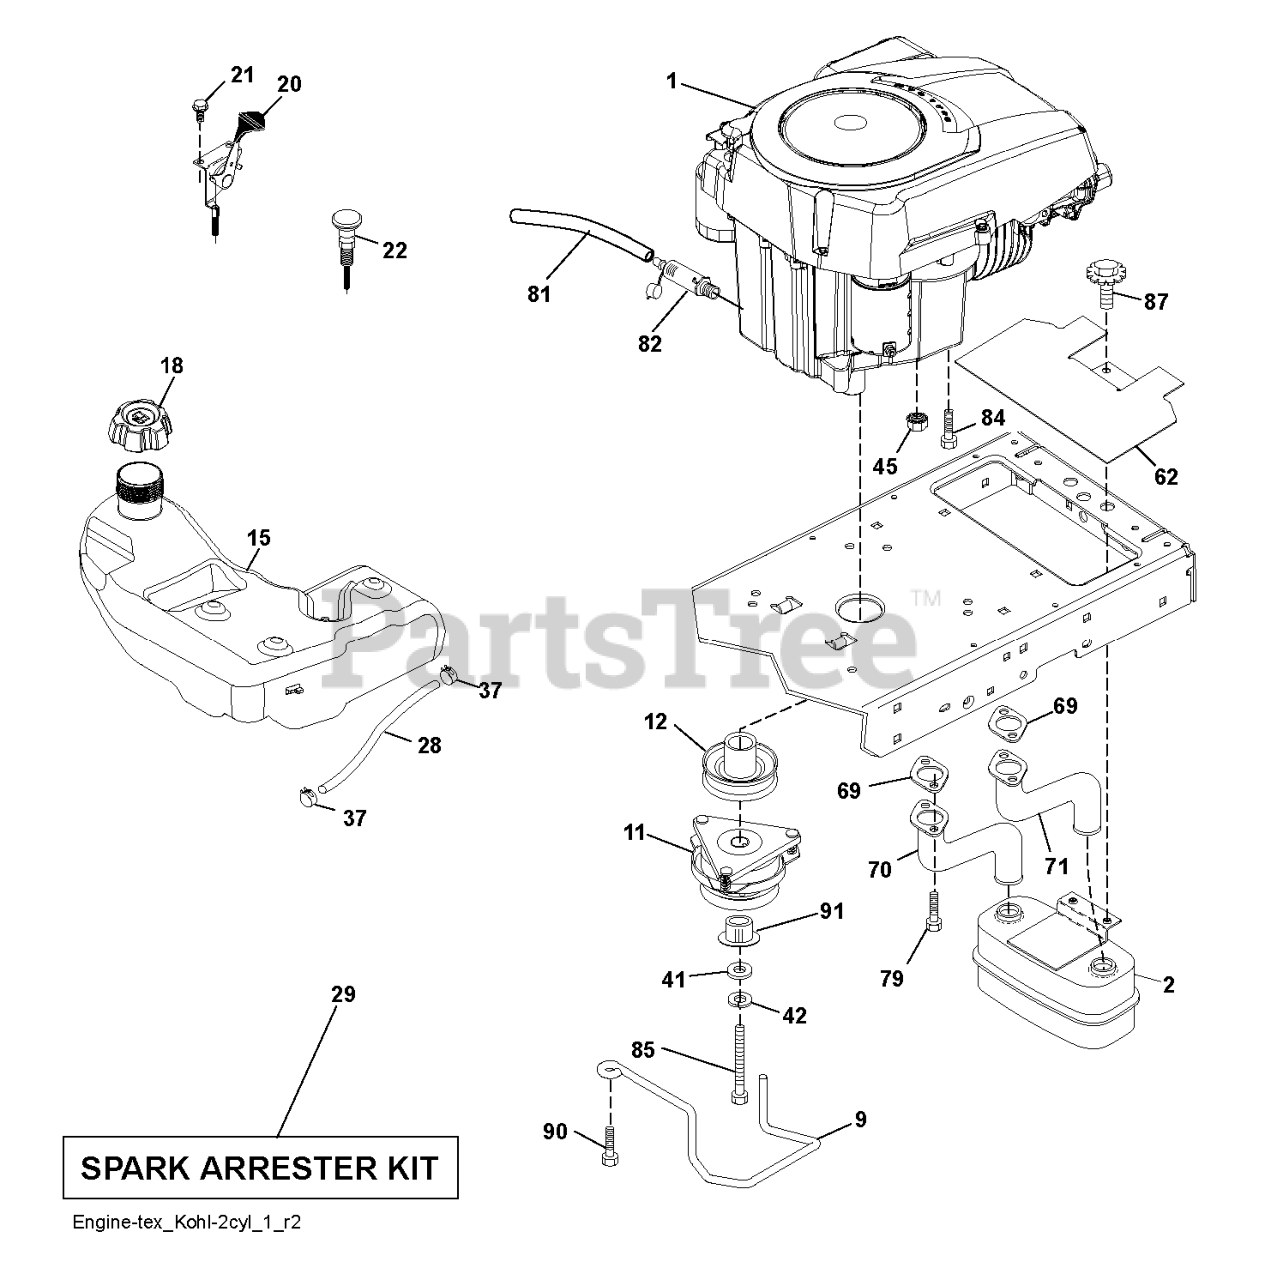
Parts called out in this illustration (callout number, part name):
2	MUFFLER.TWIN.CYL.LOW.TONE
9	KEEPER.BELT.ENGINE.4.2
11	CLUTCH MZ ZTR GT.48/54"1.125"
12	PULLEY ENGINE
15	TANK.FUEL.4GAL
18	CAP.FUEL.TANK.3"GREY
20	THROTTLE CONTROL
21	SCREW.#10 X 0.750.BOS
22	CONTROL.CHOKE.ERGO.PUSH-IN.BLA
28	REPL BY 532 00 85-43
29	KIT.SPARK ARRESTOR 794945 B&S
37	HOSE CLAMP
42	LOCKWASHER
45	NUT
62	RP SHIELD HEAT MUFFLER
69	GASKET.EXHAUST.KOHL.CV18-CV26
70	RP.PIPE-EXHAUST LH
71	RP.PIPE-EXHAUST RH
79	SCREW.SOCKET HD.5/16-1
81	TUBE, DRAIN OIL ASM.
82	PLUG DRAIN OIL EASY
84	SCREW 3/8-16X1
85	BOLT HEX 7/16-20 X 3.75 GR. 5
87	BOLT.5/16-18UNCX3/4 W/SEMS.BLK
90	SCREW 3/8-16X1
91	BUSHING.1.375OD
95	SCREW.SOCKET HD.5/16-1
